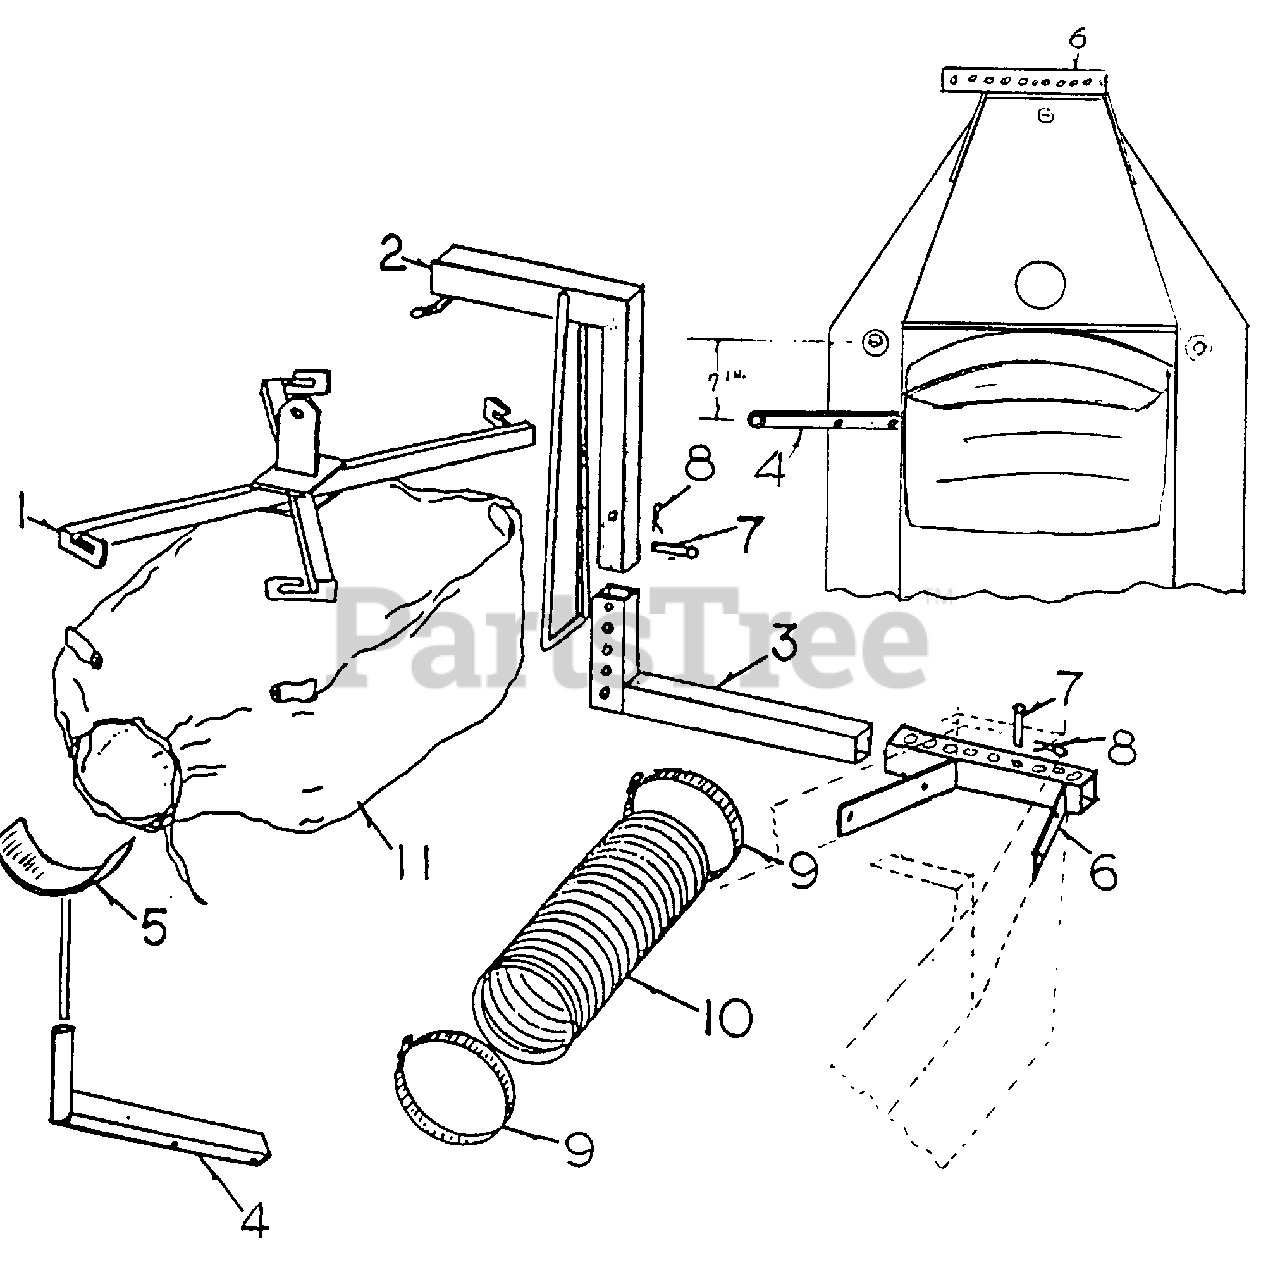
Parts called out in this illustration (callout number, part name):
1	GRASS BAG HANGER
2	VERTICAL ARM
3	HORIZONTAL ARM
4	HANCER BRACKET
4	5/16-18 Nut
5	VAC HOSE SADDLE
6	REAR MOUNTINC BRCKET
6	5/16-18 Nut
7	PINS
10	HOSE
11	BAG
